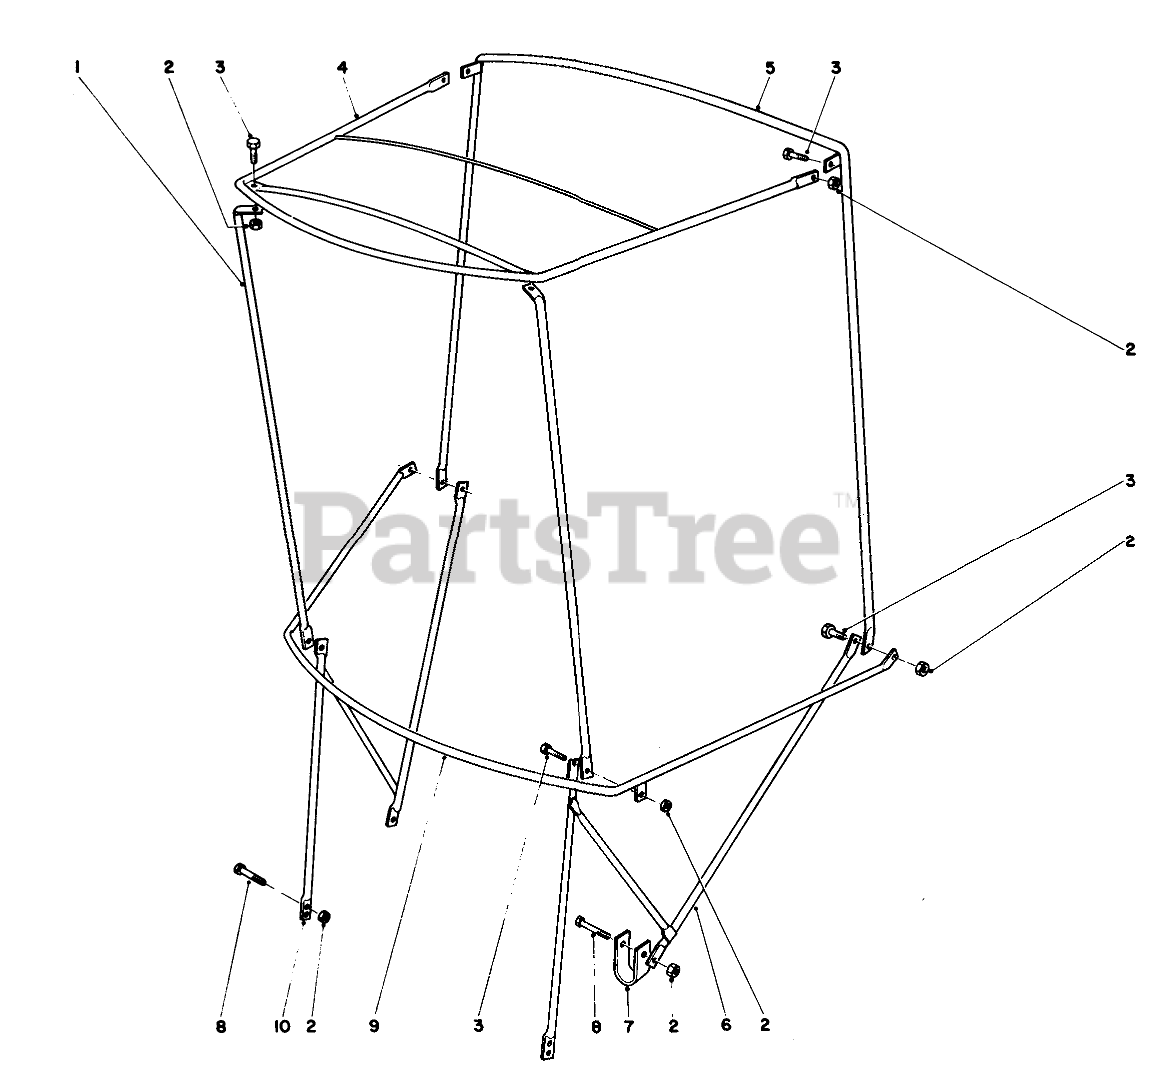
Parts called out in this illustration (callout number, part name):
2	NUT-HEX, SIDE DEFORM
3	SCREW-HH
4	FRAME-TOP
5	BOW-VERTICAL, REAR
6	ATTACHING BRKT L
7	U CLAMP
8	SCREW-HH
9	BOW-CURVED
10	ATTACHING BRKT R
